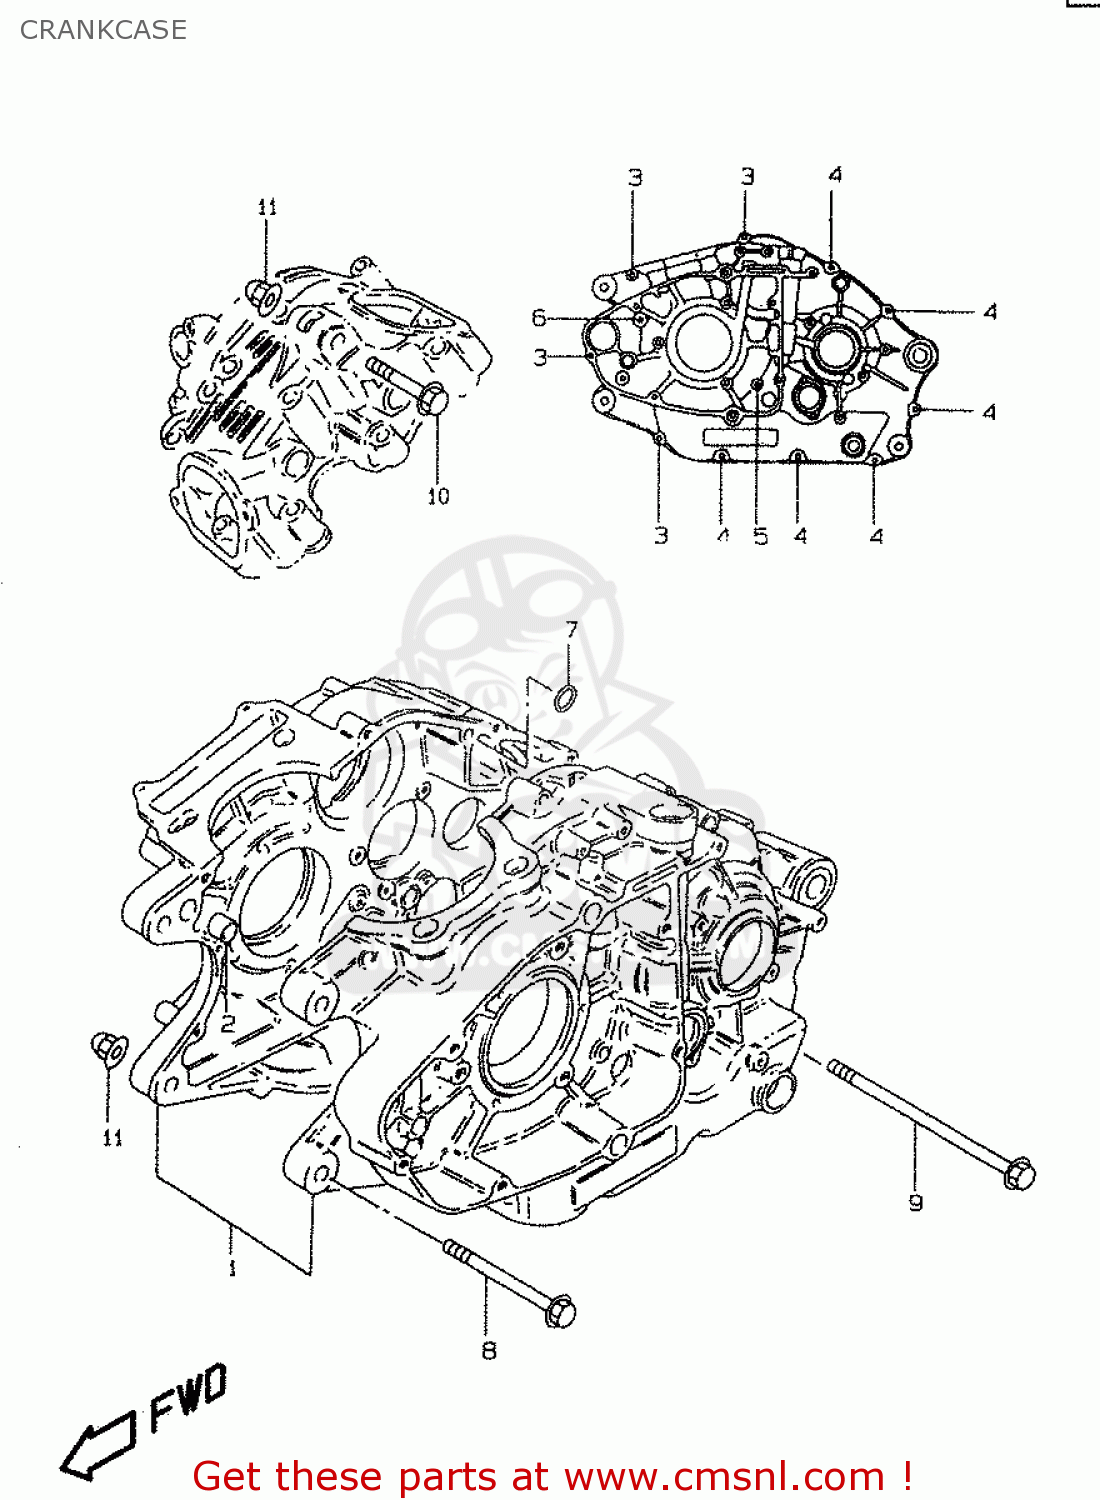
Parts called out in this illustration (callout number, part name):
1	CRANKCASE SET
2	PIN
3	BOLT
4	BOLT
5	BOLT
6	BOLT
7	O RING(D:1.9,ID:9.8)
8	BOLT(8X67)
9	BOLT(8X100)
10	BOLT(8X50)
11	NUT
